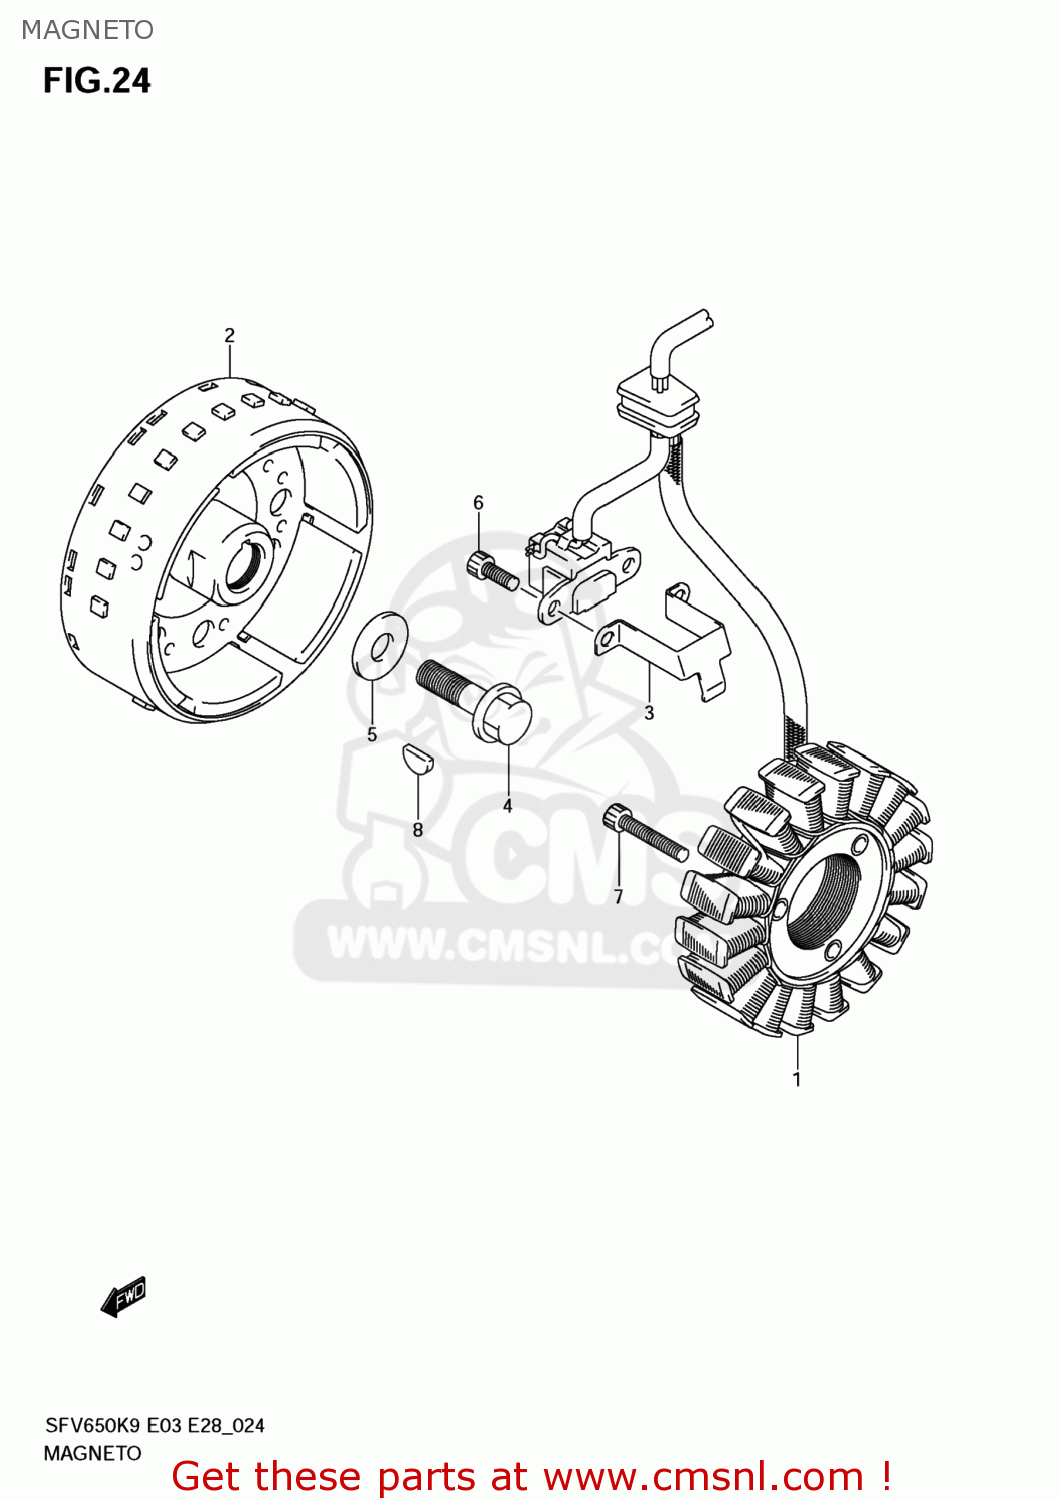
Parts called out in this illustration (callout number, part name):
1	STATOR ASSY
2	ROTOR ASSY
3	CLAMP,MAGNETO LEAD
4	BOLT(12X40)
5	WASHER(12X30X3)
6	BOLT
7	BOLT
8	KEY
